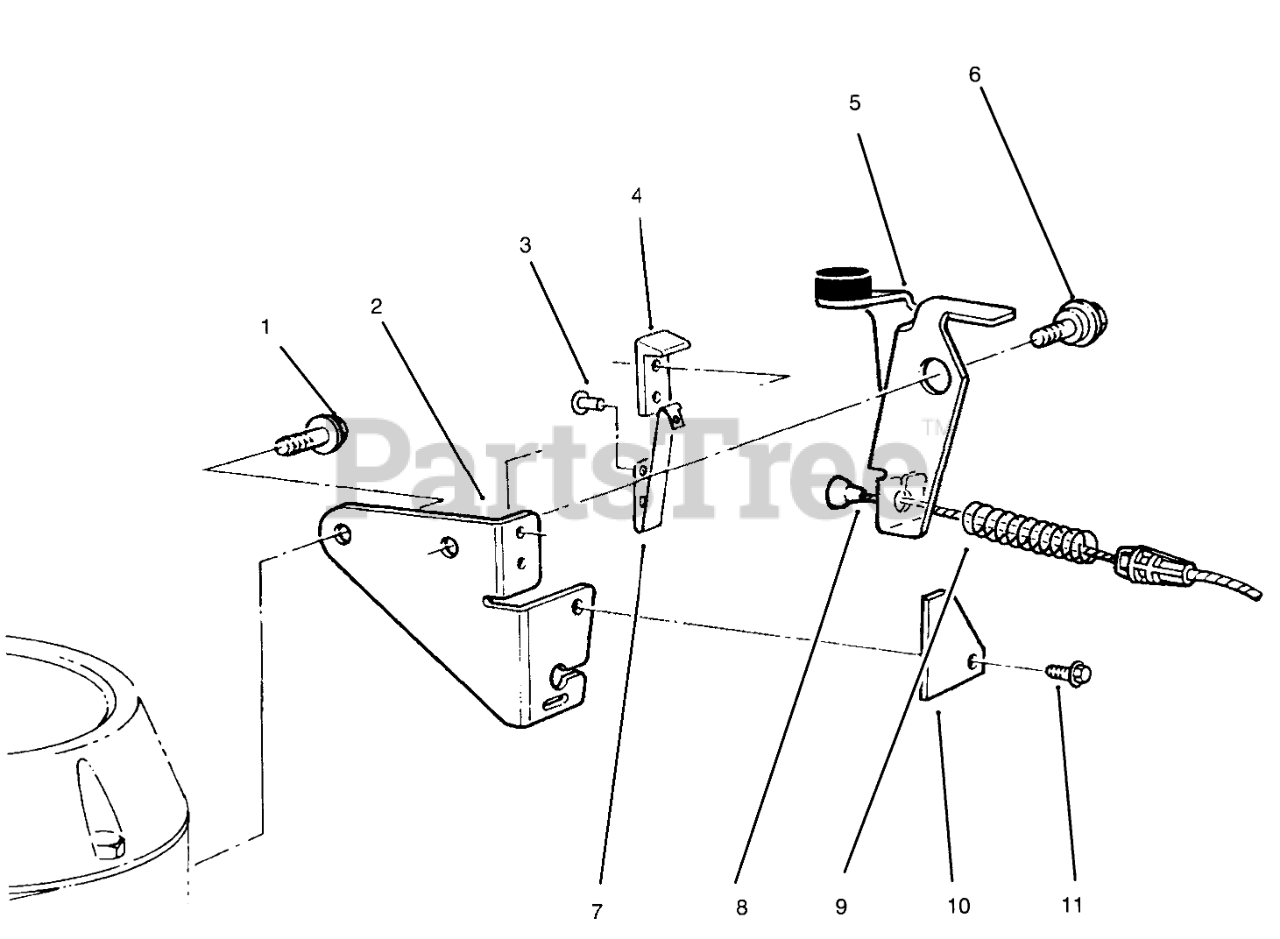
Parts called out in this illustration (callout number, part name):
1	SCREW-HWH
2	PLATE-BRAKE
3	RIVET-PLASTIC
4	STRAP-INSULATING
5	BRAKE PLATE ASM
6	SCREW-SHOULDER
7	STRAP-GROUND
8	CABLE - BRAKE
9	SPRING-COMPRESSION
10	STOP-GROUND STRAP
11	SCREW-HWH
